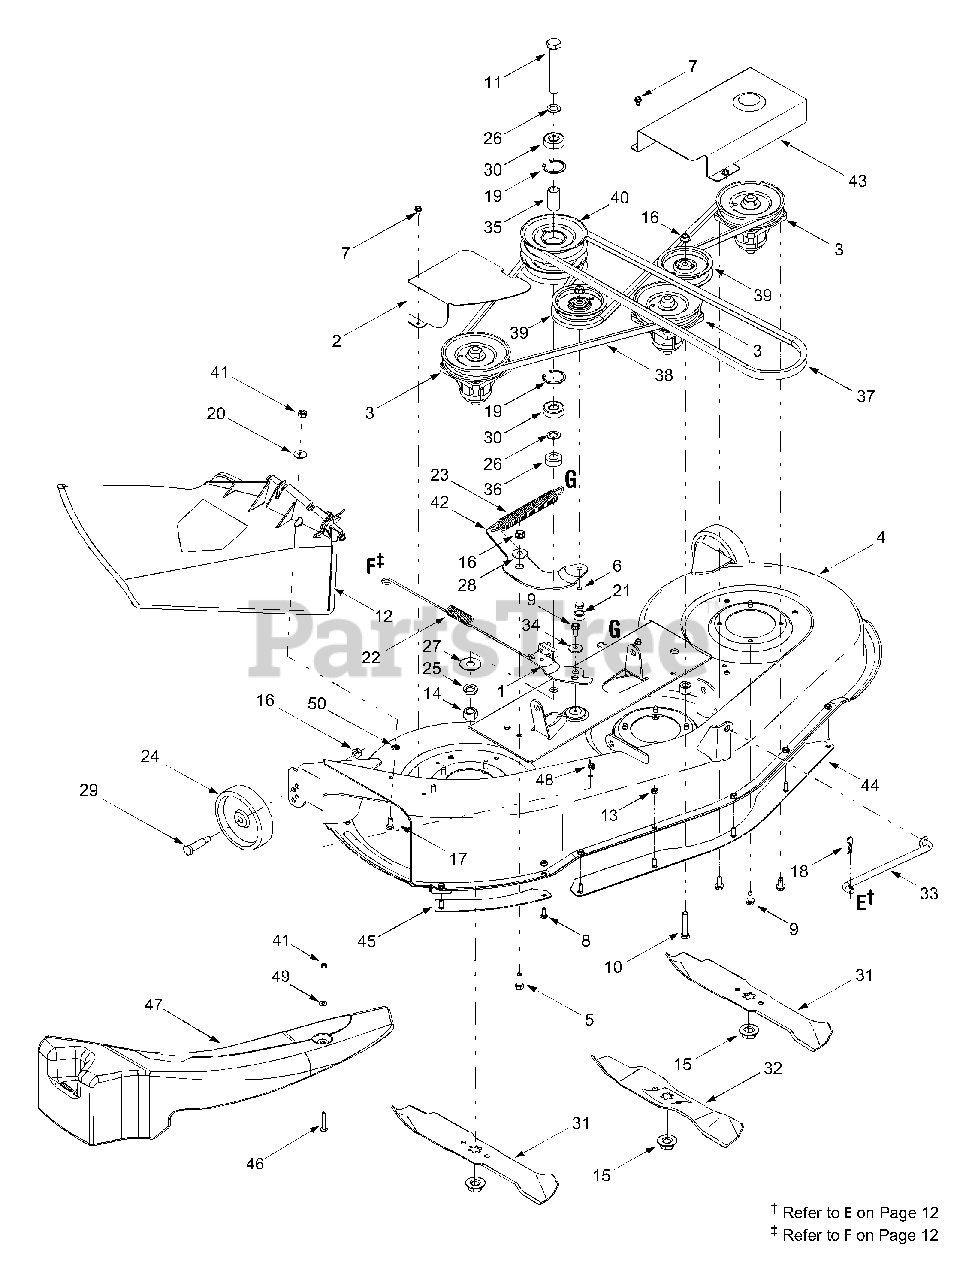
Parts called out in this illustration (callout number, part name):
1	Deck Brake Assembly
3	Spindle Assembly, 5.0 Dia.
6	Hex Cap Screw, 1/4-20 x 1.5
7	Self-tapping Screw, 1/4-20 x .5
8	Hex Cap Screw, 1/4-20 x .75
9	Screw, 5/16-18 x .75
10	Hex Cap Screw, 3/8-16 x 2.0
11	Hex Cap Screw, 5/8-18 x .875
12	Discharge Chute Assembly
13	Hex Sems Nut, 1/4-20
14	Hex Nut, 5/8-18
15	Hex Flange Nut, 5/8-18
16	Flange Lock Nut, 3/8-16
17	Hex Cap Screw:1/4-20 x .620
18	Internal Cotter Pin, .080 x 1.56
19	Internal Retaining Ring
20	Bell Washer, .265 x .75 x .062
21	Slide Cap
22	Extension Spring, .788 x 15.5
23	Extension Spring, .91 x 7.33
24	Deck Wheel, 5 x 1.38
25	Lock Washer, 5/8
26	Flat Washer, 5/8
27	Flat Washer, 1.585 x .635 x .062
28	Shoulder Spacer, .625 x 1.16
29	Shoulder Screw, .498 x 1.53
30	Bearing, .625 x 1.574 x .470
31	Three-in-one Blade, Star Center, 16.28"
32	Three-in-one Blade, Star Center, 14.88"
33	Deck Hanger Link/Anti-sway Rod
34	Shoulder Spacer
35	Spacer, .635 x .88 x 1.72
36	Spacer, .635 x 1.25 x .445
37	PTO Belt (Upper Deck Belt)
38	Deck Belt (Lower Deck Belt)
39	Idler Pulley, 3.5
40	Double Pulley, 5.0
41	Hex Nut, 1/4-20
46	Screw, 1/4-20 x 1.5
47	Mulch Plug
48	Wing Nut, 1/4-20
49	Flat Washer, 28 X .74 X .063
50	Push Nut, 1/4
